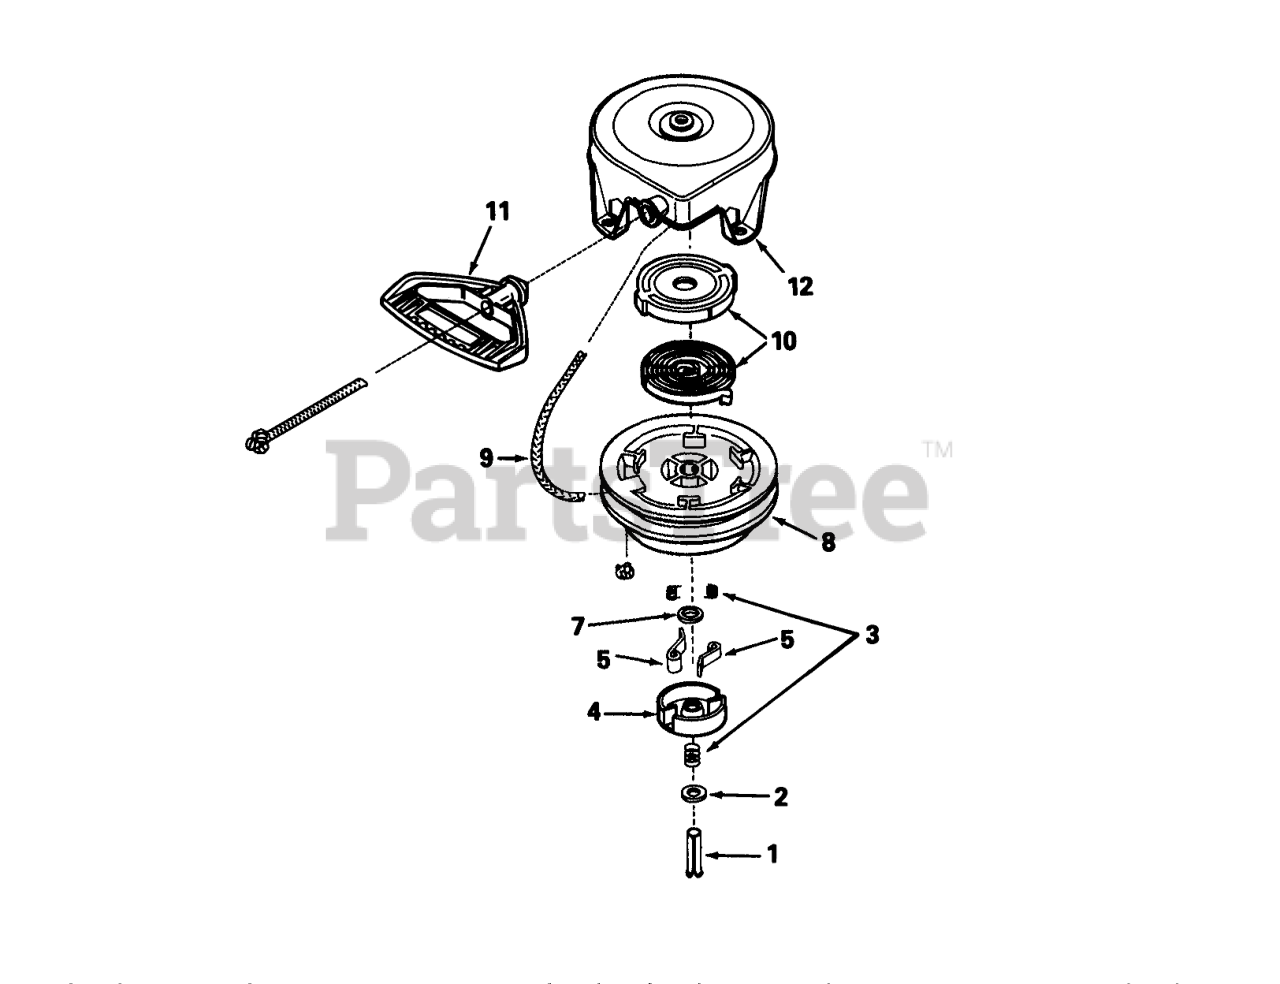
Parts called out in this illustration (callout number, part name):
1	Pin-Spring (Incl. Ref. #7)
3	Spring Assembly
4	Retainer
5	Dog-Starter
9	Rope-Starter
10	Spring & Keeper Assy.
11	Handle-Starter, Mitten Grip
12	Housing Assy., Starter
